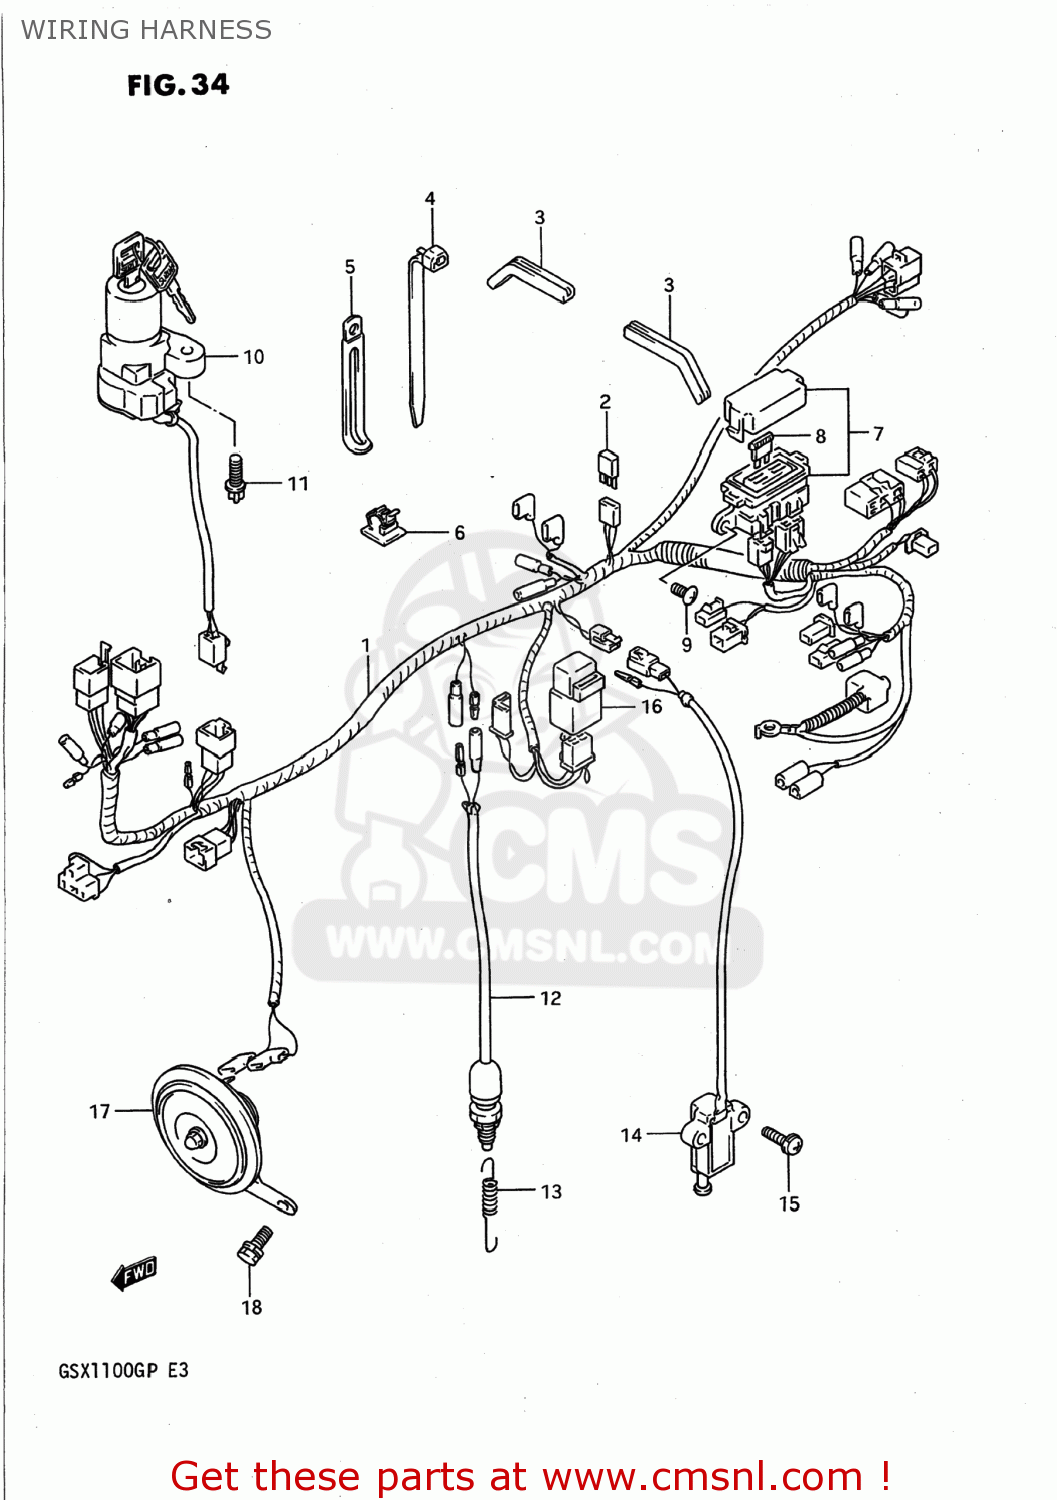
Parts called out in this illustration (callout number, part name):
1	HARNESS,WIRING
2	DIODE(STANLEY DE8804)
3	PROTECTOR,WIRING HARNESS
4	CLAMP
5	CLAMP
6	CLAMP
7	BOX ASSEMBLY,FUSE
8	FUSE(10A)
9	SCREW
10	LOCK ASSEMBLY,STEERING
11	SCREW(6X18)
12	SWITCH ASSY,STOP LAMP
13	SPRING
14	SWITCH ASSEMBLY,SIDE STAND
15	SCREW
16	RELAY ASSEMBLY
17	HORN ASSEMBLY
18	BOLT ,6X12
19	KEY,BLANK
